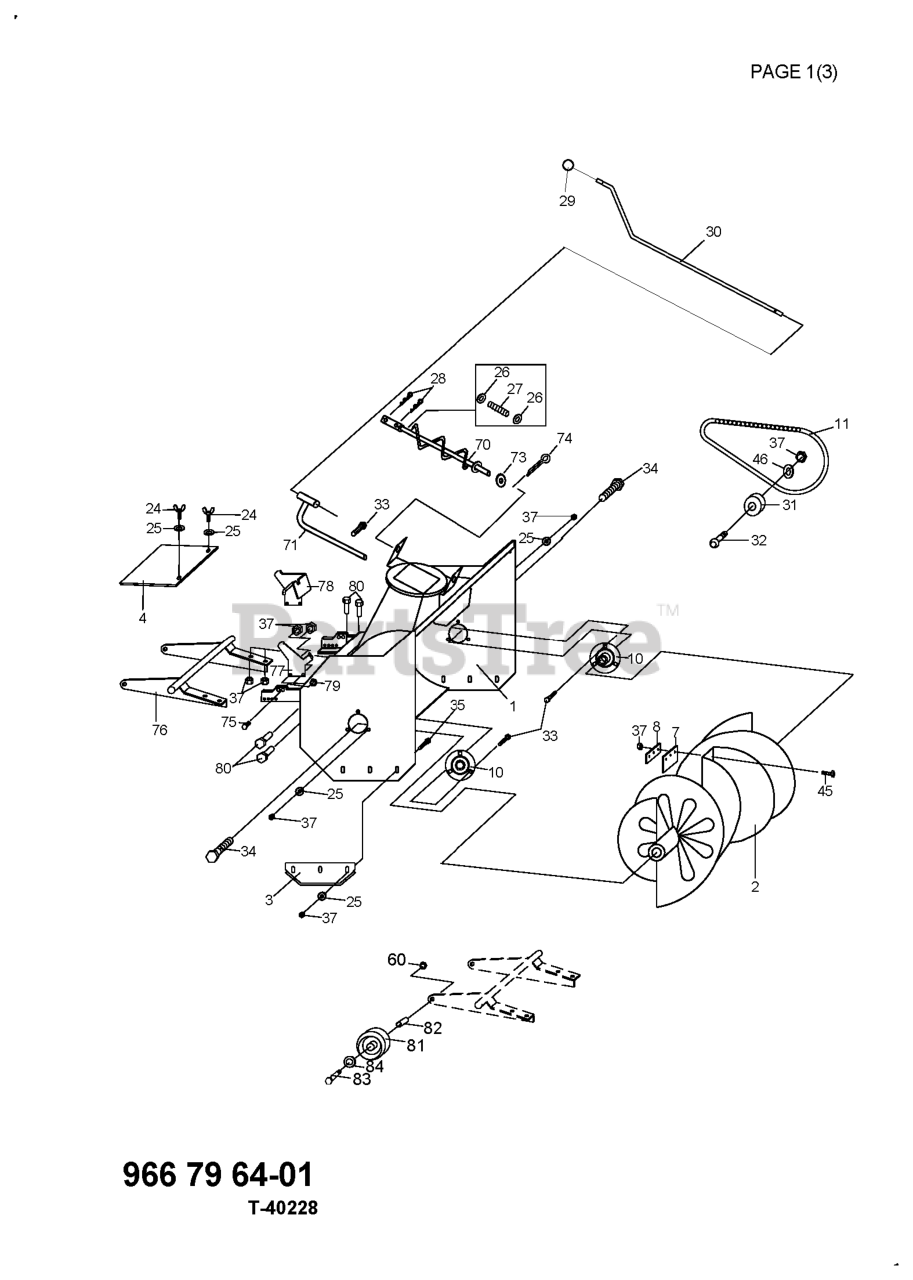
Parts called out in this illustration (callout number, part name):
7	PROTECTION
28	PIN RETAINING SCREW
31	CHAIN TENSIONER
74	PIN RETAINING SCREW
81	SUPPORT WHEEL
82	COLLAR
